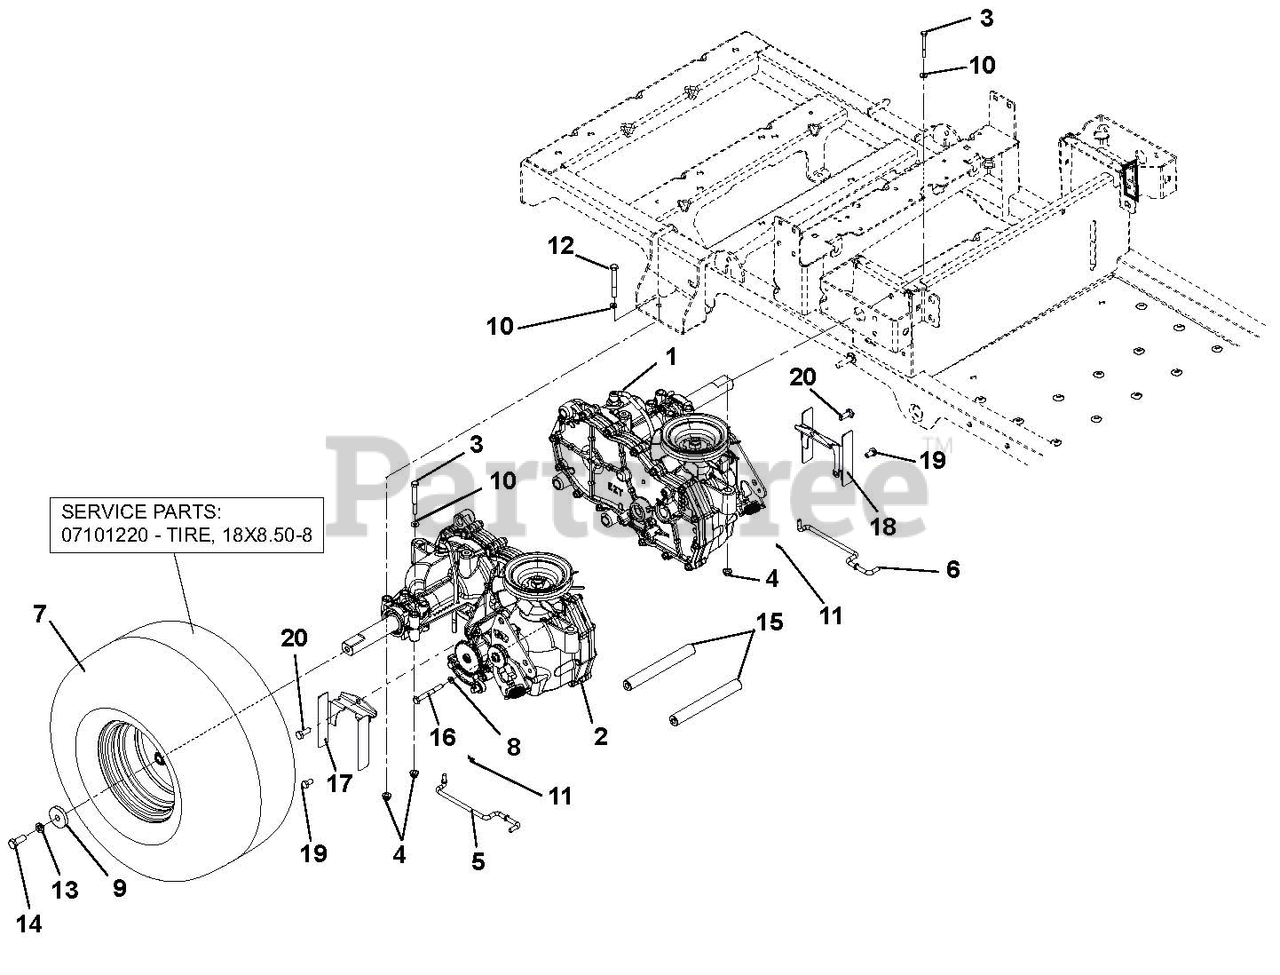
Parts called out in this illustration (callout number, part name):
1	TRANSAXLE, LH EZT D-SHAFT LONG
2	TRANSAXLE, RH EZT D-SHAFT LONG
3	BLT, HEX .31-18X2.25 G5 ZCC
4	NUT,LK-NYL-FLG .31-18 G5ZC120
5	DUMPVALVE, RH LCZ
6	DUMPVALVE, LH LCZ
7	ASM, WHL/TIRE 18X8.50-8 DHUB
7	TIRE, 18X8.50-8
8	WSHR, FLT .406X1.00X.188 ZCC
9	WSHR, FLT .406X1.50X.245 ZCC
10	WSHR,FLT .375X.875X.083 ZCC
11	PIN, HAIR #178 .06X.77 ZCC
12	BLT, HEX .31-18X2.75 G5 ZCC
13	WSHR,LK-REG .375X.094 ZCC
14	BLT, HEX .38-16X1.00 G8ZCCEP30
15	SHAFT, TRANSAXLE BRACE
16	BLT, HEX .38-16X2.50 G5 ZCC
17	GUARD, CE RH PARKING BRAKE
18	GUARD, CE LH PARKING BRAKE
19	BLT, HEX .25-20X.625 G5 ZCC
20	BLT-HEX .25-20X.875
